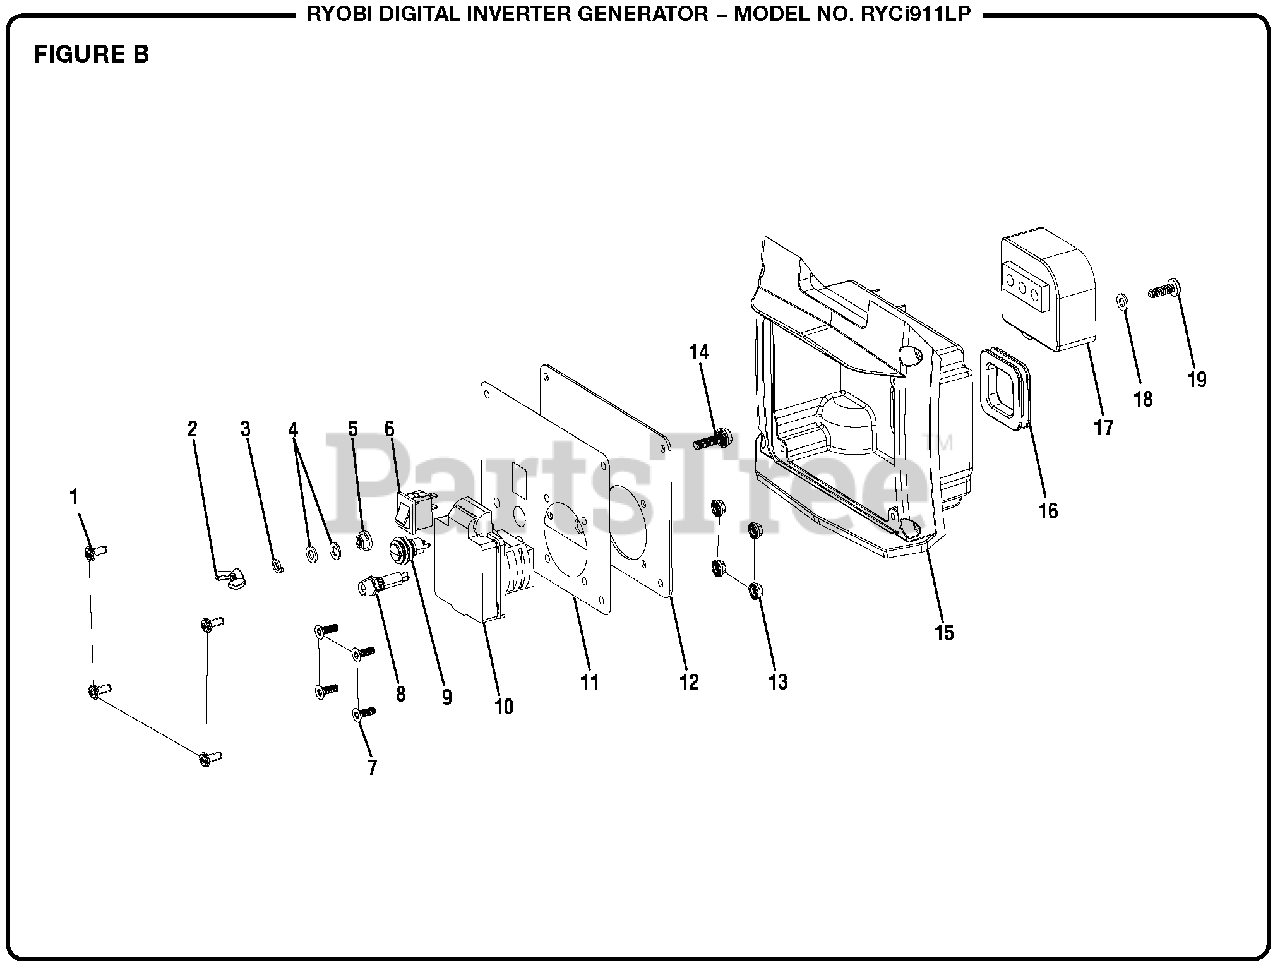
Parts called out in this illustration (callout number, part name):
1	Screw (M4 x 13 mm, Flat Hd.)
2	Wingnut (M5)
3	Washer (ID5 x OD8 x 1.4t)
4	Washer (ID5.3 x OD10 x 1t)
5	Lock Nut (M5)
6	On/Off Switch
7	Screw (M4 x 10 mm, T-20 Torx Pan Hd.)
8	Indicator (Red LED)
9	Reset Button
10	120V-15A Single Receptacle
11	Control Panel Label
12	Control Panel Faceplate
13	Lock Nut (M4)
14	Screw (M5 x 18 mm, Flange Hex Hd.)
15	Control Panel Housing
16	Rubber Grommet
17	Ignition Module (700W)
18	Washer (ID5.2 x OD10 x 1t)
19	Screw (M5 x 16 mm, T-25 Torx Pan Hd.)
